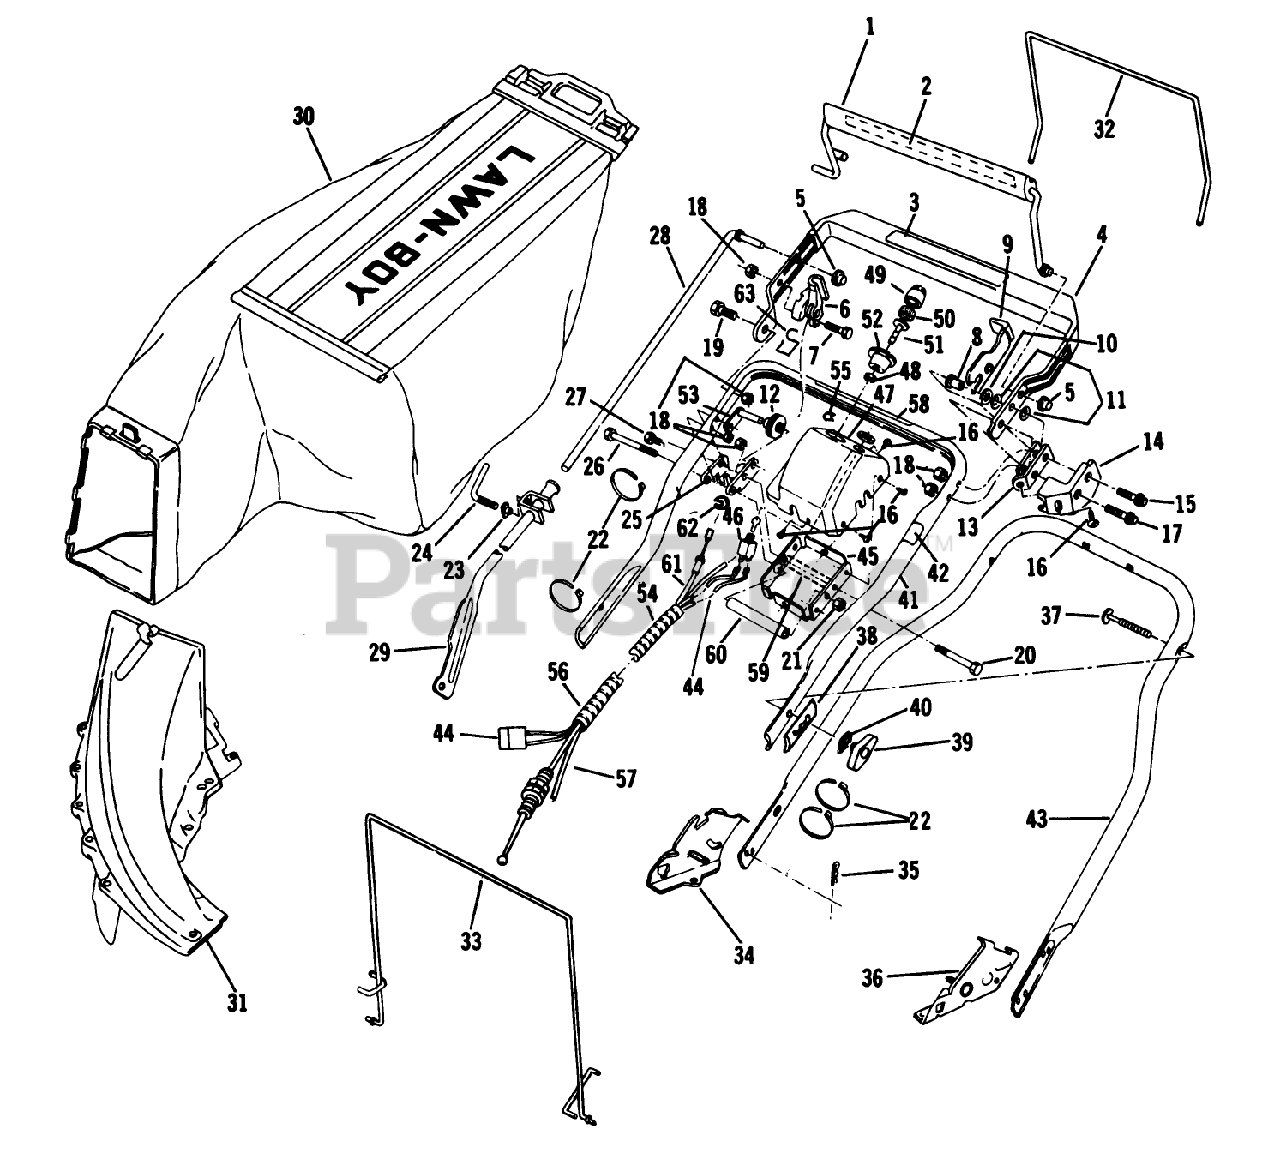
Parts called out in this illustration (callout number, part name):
8	SPACER
10	WASHER M
13	DOWN STOP
14	LOCKOUT GUARD
15	BOLT SHOU
16	SCREW F
17	Bolt-Shoulder-L.H.
18	LOCKNUT E
19	BOLT
26	BOLT-CONSOLE
28	CONTROL ROD
32	HANGER
33	HANGER AY
34	BRACKET ASM - HANDLE, SP, RH
35	HAIR PIN
36	BRACKET ASM - HANDLE, SP, LH
37	BOLT QUALITY
38	BRACKET R/B 613462
39	NUT-WING
40	WASHER-CURVED
48	LOCKNUT S
50	FILTER S
59	SPACER
61	CONTROL CABLE
62	RET. RING
